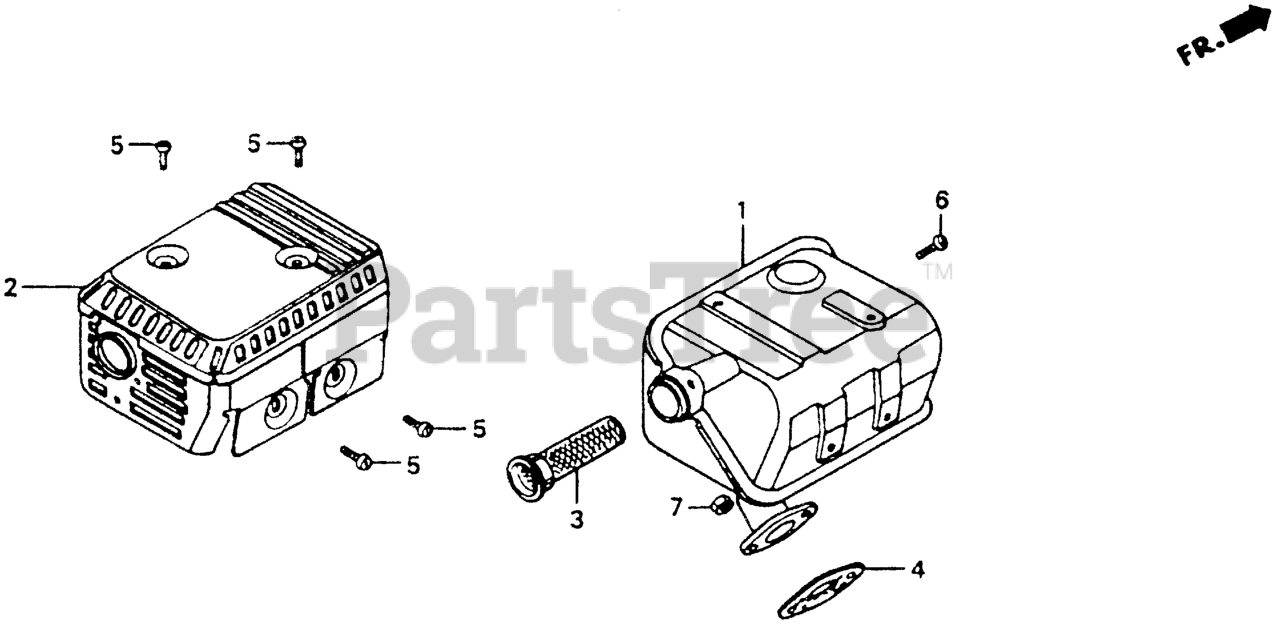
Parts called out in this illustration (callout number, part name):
1	MUFFLER (STD) Use up to Engine SN 1869307.
1	MUFFLER (ARRESTER)
1	MUFFLER (ARRESTER) Use from Engine SN 1870783.
2	PROTECTOR, MUFFLER (ALUMINIZED)
3	ARRESTER, SPARK
4	GASKET, MUFFLER
5	SCREW, TAPPING (5X8)
6	SCREW, TAPPING (4X6) (TO INSTALL OPTIONAL SPARK ARRESTER)
7	NUT, HEX. (8MM)
